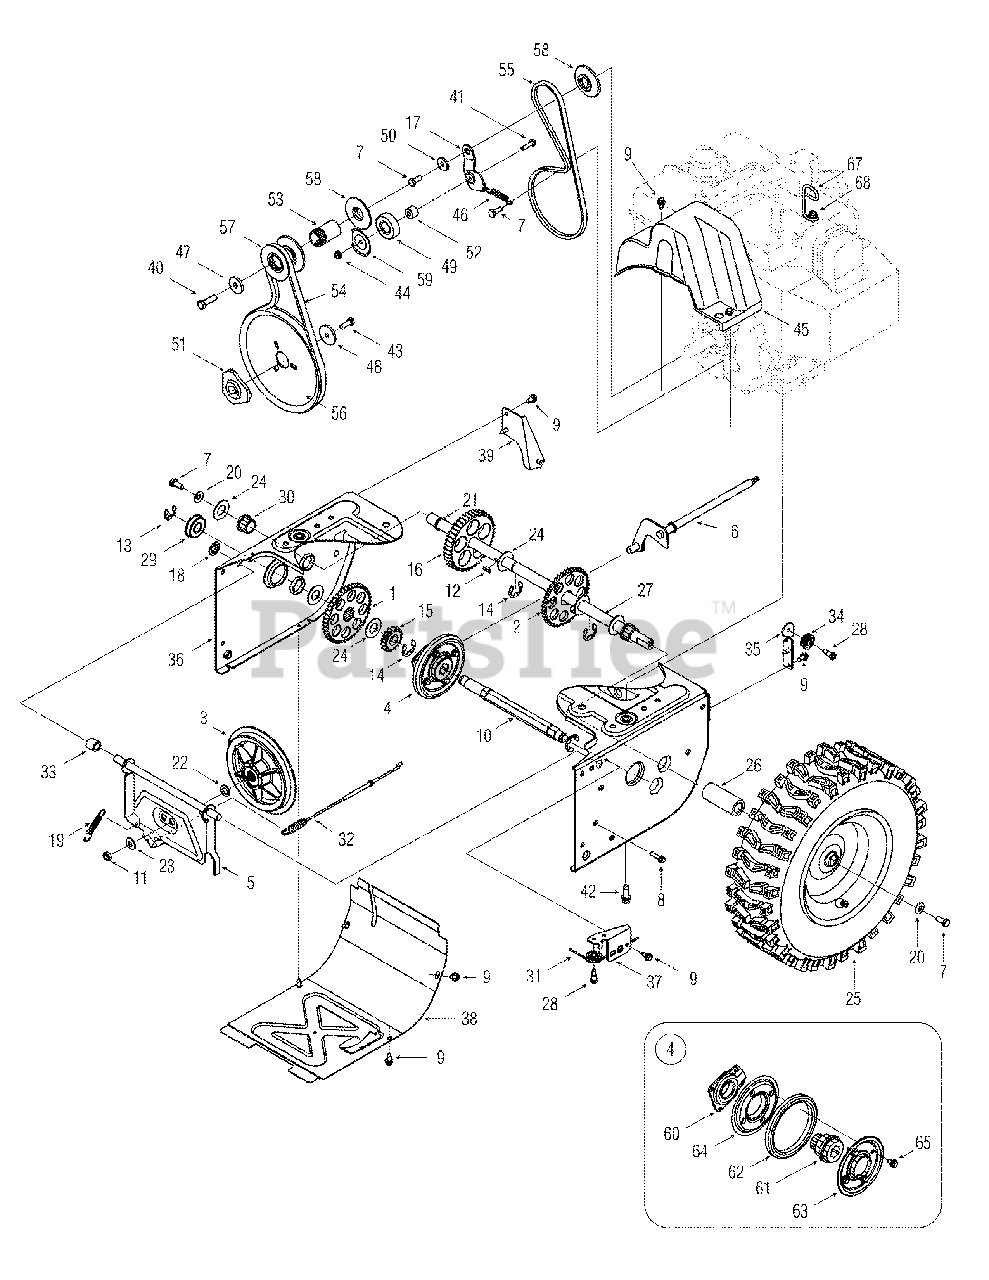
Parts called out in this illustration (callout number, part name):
2	Gear Assembly, 16/44T
3	Disc Assembly, Friction Wheel,.375
4	Wheel Assembly, Friction, 4.9 OD
7	Screw, 5/16-24 x.750, Gr5
8	Screw, 1/4-20 x 1.000
9	Screw, 1/4-20 x.625
10	Hex Shaft, Drive,.75
11	Nut, Jam, 3/8-24, Gr2
12	Key, Hi-pro 3/16 x 5/8
13	Ring, E Type,.750
14	Ring, E-Type,.875
15	Pinion, 16T
16	Gear, 44T
19	Extension Spring
20	Washer, Bell,.340 x.872 x.060
21	Washer, Flat,.75 x 1.00 x.060
22	Washer, Flat,.406 x.875 x.059
23	Washer, Bell,.375 x.870 x.063
24	Washer, Flat,.793 x 1.24 x.060
25	Wheel Assembly Complete, Wheel Size 13 x 4
25	Wheel Assembly Complete, Wheel Size 15 x 5
26	Spacer, 1.25 OD x.75 ID x 3.00
27	Axle,.75 x 22
28	Screw, 1/4-28 x.375
29	Bearing, Ball, 17 x 40 x 12
30	Bearing, Hex Flange x.75 ID
31	Cable, Auger, 44.75
32	Cable, Drive, 41.75
33	Spacer,.508 ID x.75 OD x.68
34	Roller, Cable
41	Screw, 1/4-20 x 1.00, Gr5
42	Screw, Sems, 3/8-16 x 1.00
43	Screw, 5/16-24 x.875, Gr8
44	Nut, Flange Lock, Nylon, 1/4-20, Gr F
45	Cover, Belt
46	Spring, Extension,.38 OD x 2.68
47	Washer, Flat,.406 x 1.25 x.157
48	Washer, Flat,.34 x 1.50 x.150
49	Bearing, Ball, 20 x 47 x 14
50	Shoulder Spacer
51	Pulley, Adapter,.75 Dia.
52	Spacer,.777 OD x.260 ID x.550
53	Spacer,.875 ID x 1.185 OD
54	V-Belt, 1/2"
55	V-Belt, 3/8"
56	Pulley, Auger, 8.1 x.50
57	Pulley, Half, 2.600 OD
58	Pulley, Half, 2.2 OD
59	Washer, Bearing, 2.12 OD x.255 ID
60	Bearing Assembly, Friction Wheel
61	Hub, Friction Wheel
62	Friction Wheel Rubber, 4.875 OD
63	Plate, Friction, 12 Pt 4.60 Dia
64	Plate, Friction, Extrs, 12 Pt 4.60 Dia
65	Screw, Self-tapping, 1/4-14 x 0.625
67	Chute Cable Guide
68	Screw, 5/16-18 x 1.00
